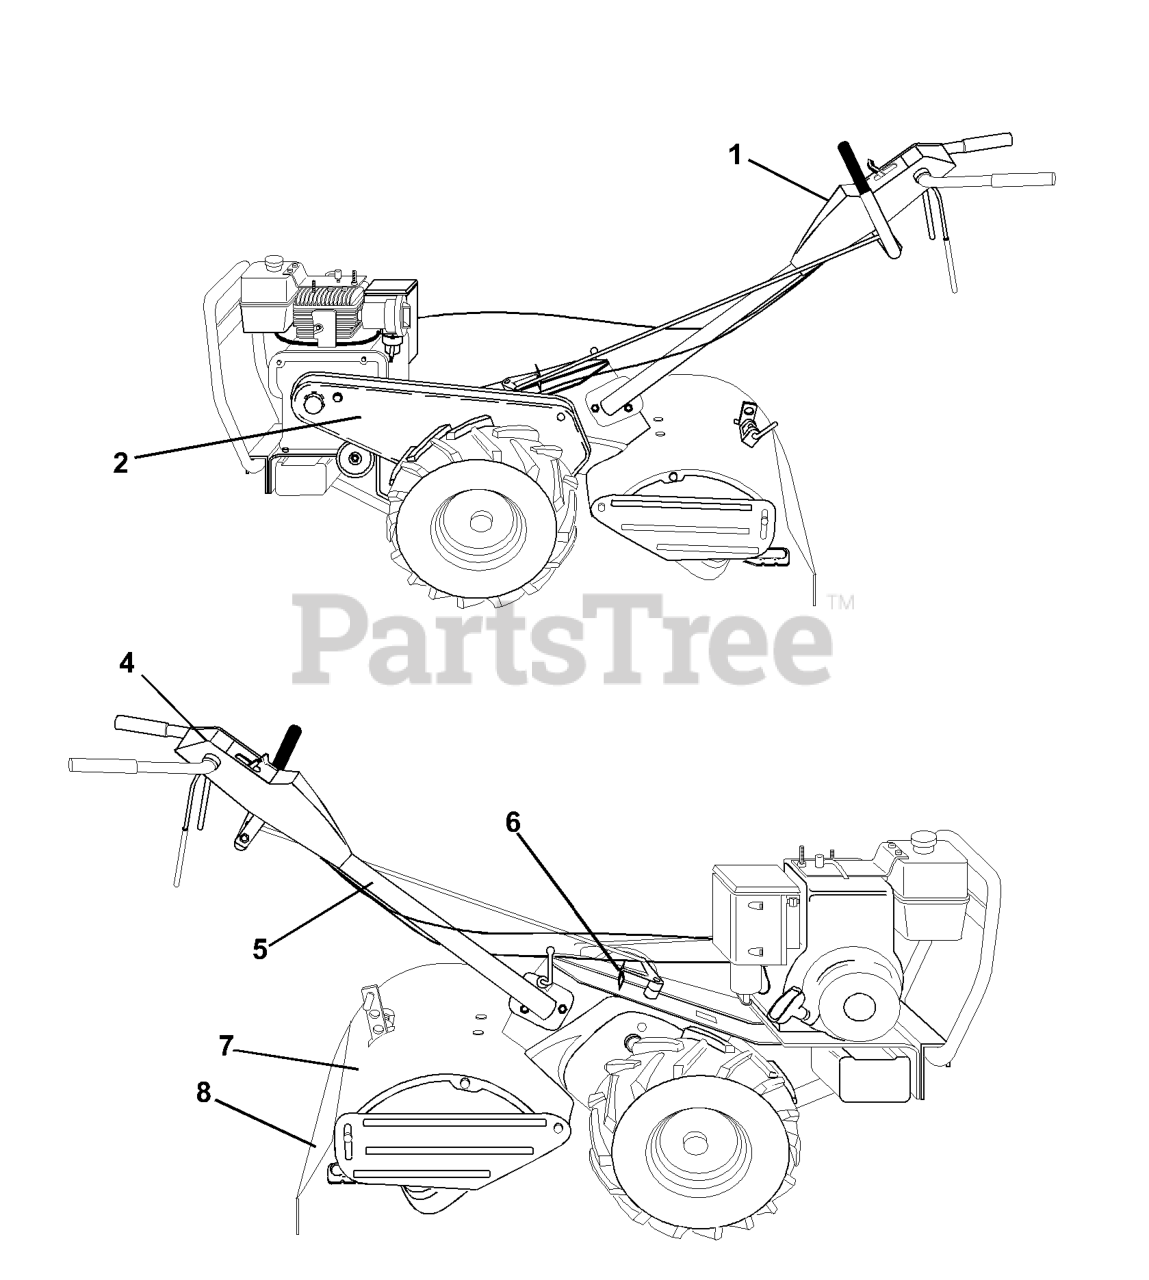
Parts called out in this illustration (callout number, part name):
1	DECAL, LOGO
2	SHIELD DECAL
4	DECAL INSTRUCTION
5	DECAL TI (2 2)
6	DECAL, SHIFT INDICATOR
7	DECAL -CAUTION
8	DECAL TI
